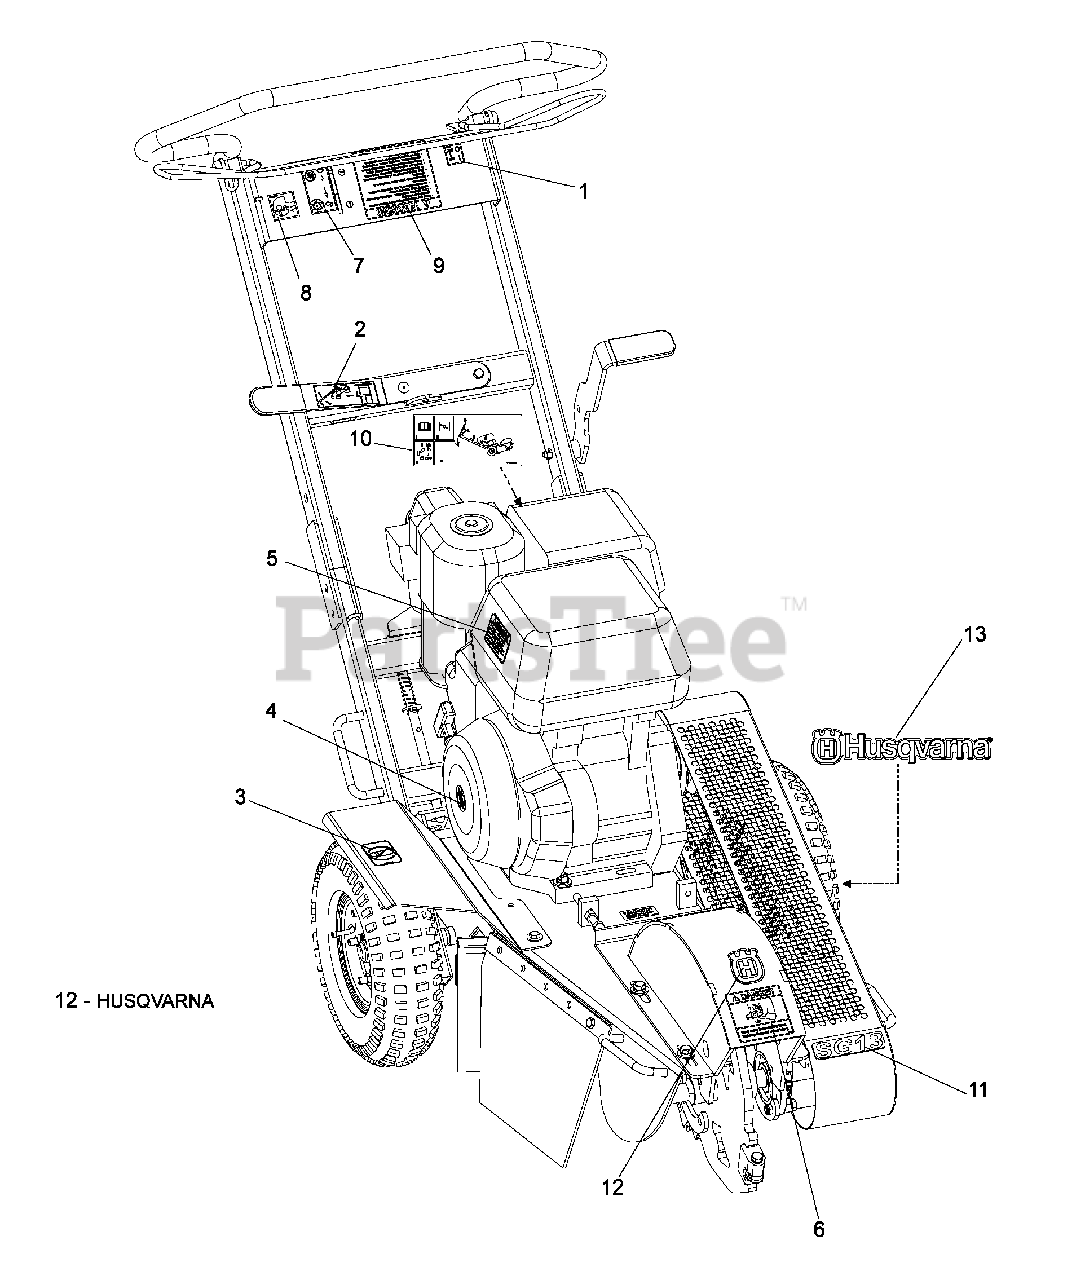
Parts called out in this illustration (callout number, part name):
1	DECAL, ON/OFF
2	DECAL, HANDLE ADJ
3	DECAL, NO STEP
4	DECAL, HONDA STARTER
5	DECAL, PROP 65
6	DECAL, DANGER FOOT
7	DECAL, THROTTLE
8	DECAL, EAR/EYE WARN
9	DECAL, CAUTION LIST
10	DECAL, OPERATION
11	DECAL, SG13
12	DECAL, CROWN
13	DECAL, HUSQVARNA
